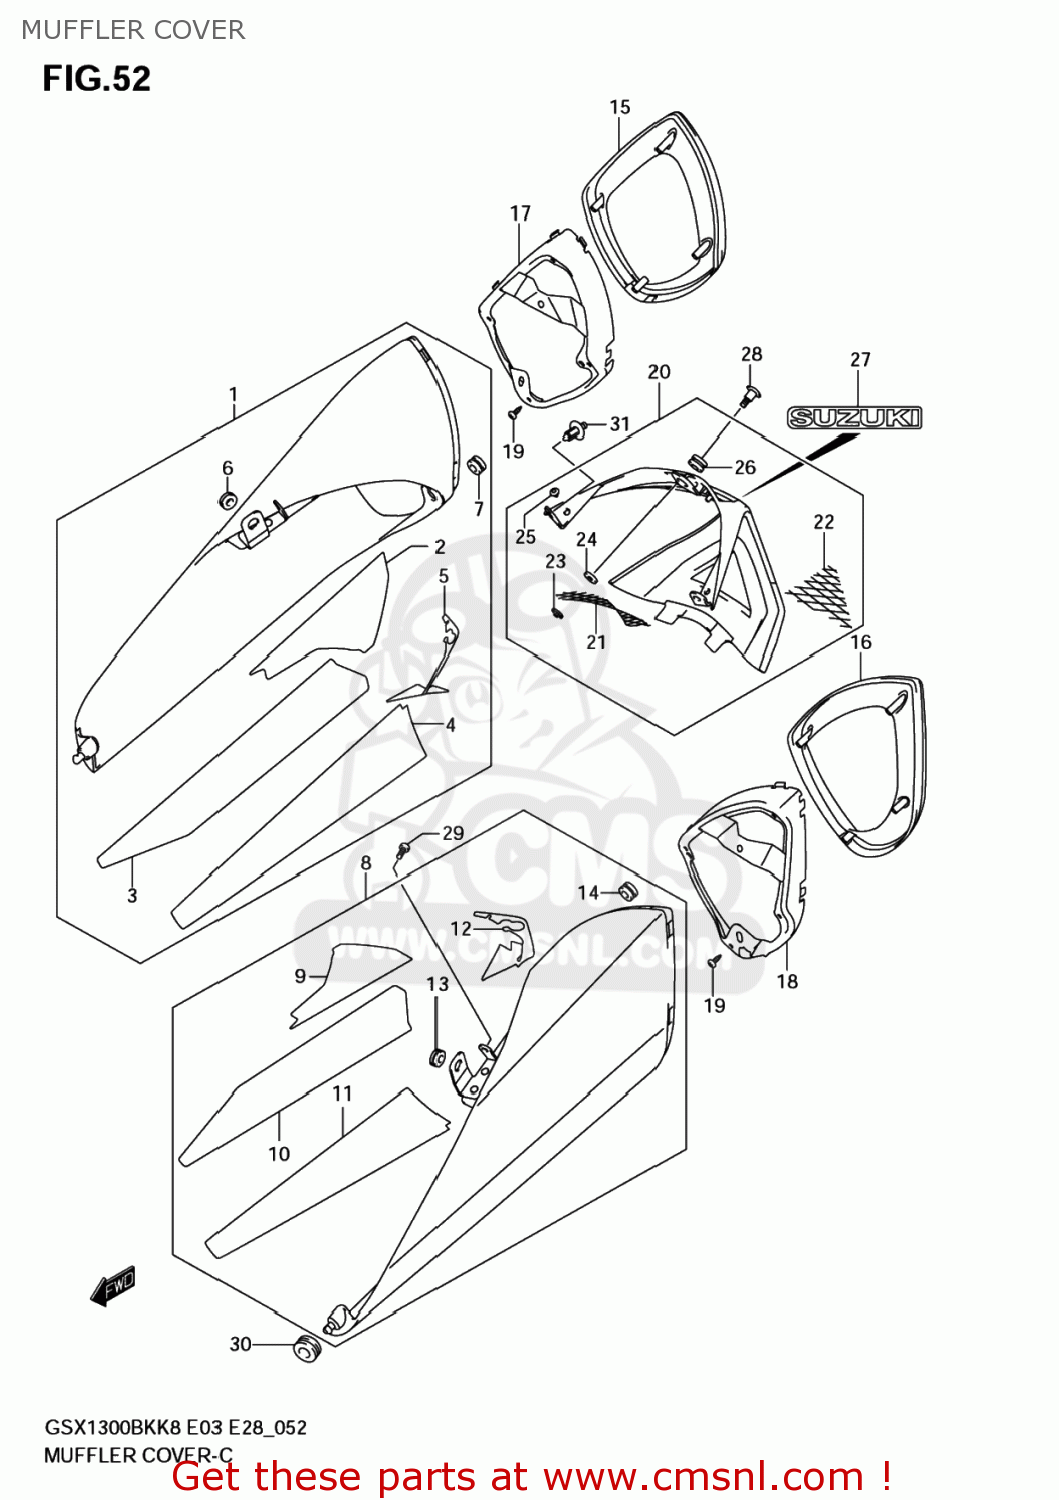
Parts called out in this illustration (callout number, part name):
1	COVER,MUFFLER,R(BLACK)
2	SHIELD,MUFFLER COVER,R NO.1
3	SHIELD,MUFFLER COVER,R NO.2
4	SHIELD,MUFFLER COVER,R NO.3
5	SHIELD,MUFFLER COVER,R NO.4
6	CUSHION
7	CUSHION
8	COVER,MUFFLER,L(BLACK)
9	SHIELD,MUFFLER COVER,L NO.1
10	SHIELD,MUFFLER COVER,L NO.2
11	SHIELD,MUFFLER COVER,L NO.3
12	SHIELD,MUFFLER COVER,L NO.4
13	CUSHION
14	CUSHION
15	COVER,MUFFLER TAIL,R(SILVER)
16	COVER,MUFFLER TAIL,L(SILVER)
17	BRACKET,MUFFLER COV TAIL,R
18	BRACKET,MUFFLER COV TAIL,L
19	SCREW
20	COVER,MUFFLER CTR
21	NET,MUFFLER COVER CTR
22	NET,MUFFLER CENTER COVER LWR
23	NUT
24	CUSHION
25	PLUG(OD:10)
26	CUSHION
27	EMBLEM,SUZUKI
28	SCREW(6X20)
29	SCREW(6X12)
30	CUSHION
31	CLIP
